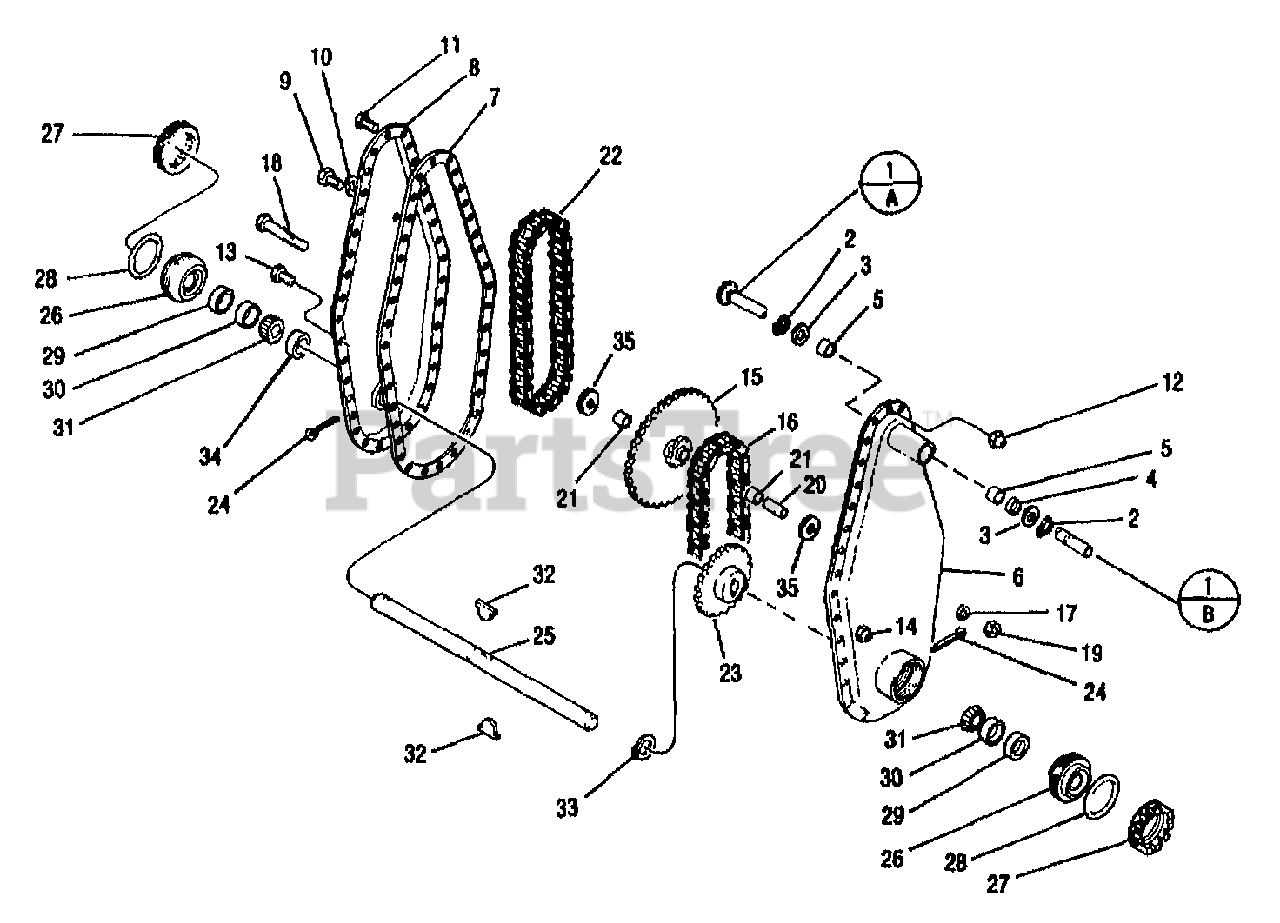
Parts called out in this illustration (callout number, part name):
1	ASSM-INPUT PTO SHAFT
2	RING-RETAIN EXT .707 ID
3	WASHER-THRUST
4	SEAL-OIL 3/4 DIAMETER
5	BEARING-NEEDLE 3/4
6	ASSM-HOUSING LH
7	GASKET-CHAIN CASE
8	ASSM-HOUSING RH
9	SCR-HH 1/2-20X.75 G5 ZP
10	WASHER-1.0X.53X.06 NYLON
11	SCR-HH 1/4-20X.625 G5 ZP
12	NUT-HT LK 1/4-20
13	SCR-HHC 5/16-18X.75 GR 5 ZP
14	NUT-TOP/LK 5/16-18 ZP
15	ASSM-SPROCKET
16	CHAIN-DRIVE ASA 50
17	WASHER-LK .375 @ DEPL
18	SCR-HH 3/8-16X2.75 G5 ZP
19	NUT-LOCK 3/8-16
20	SLEEVE-IDLER
21	BEARING-NEEDLE 1/2
22	CHAIN-DRIVE ASA 41
23	ASSM-SPROCKET 24T
24	PIN-COTTER .120X1.00 ZP
25	SHAFT-TINE
26	BEARING-CARRIER
27	RING-LOCKING
28	RING-O 3.35 ID
29	SEAL-OIL 1.25
30	BEARING-CUP
31	BRG-TAPERED ROLLER CONE
32	KEY-HI PRO .25X.875
33	RING-RET. EXT 1.25 ID
34	SPACER-1.75X1.265X.5
35	WASHER-THRUST .79X.37X.03
